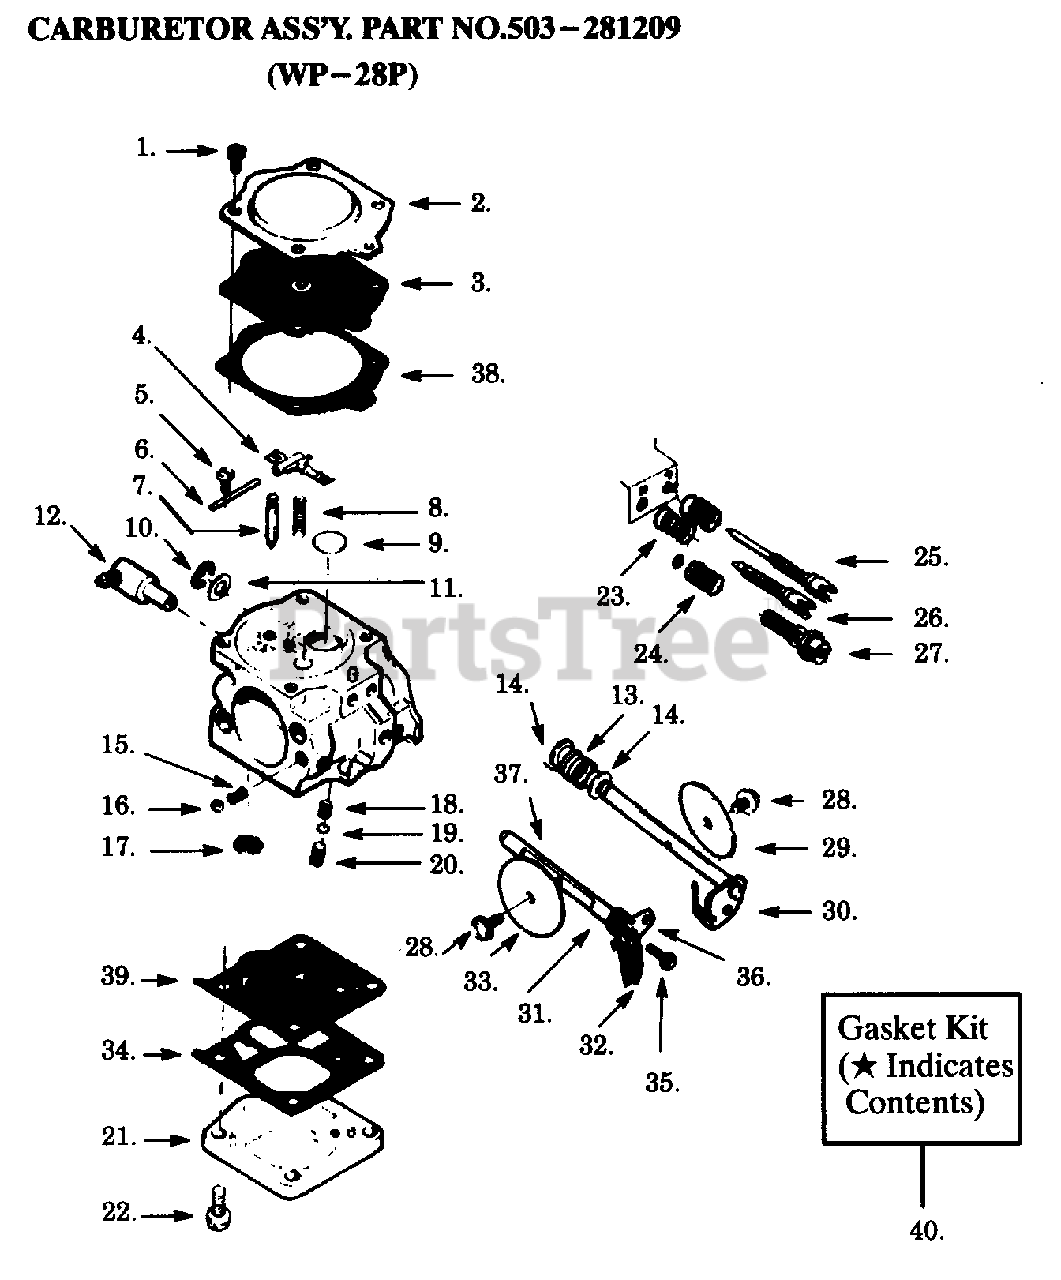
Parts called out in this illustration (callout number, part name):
1	Screw
3	Diaphragm
4	Metering Lever
13	Spring Return
21	Cover-Pump
23	Spring
24	Spring
25	Needle-Low
26	Needle-High
27	Idle Screw
30	Shaft Ass'y.
34	Gasket-Pump
37	Choke Shaft
39	Diaphragm-Pump
40	Gasket Kit (Inc. 3,4,7,8,17,34,38,39)
